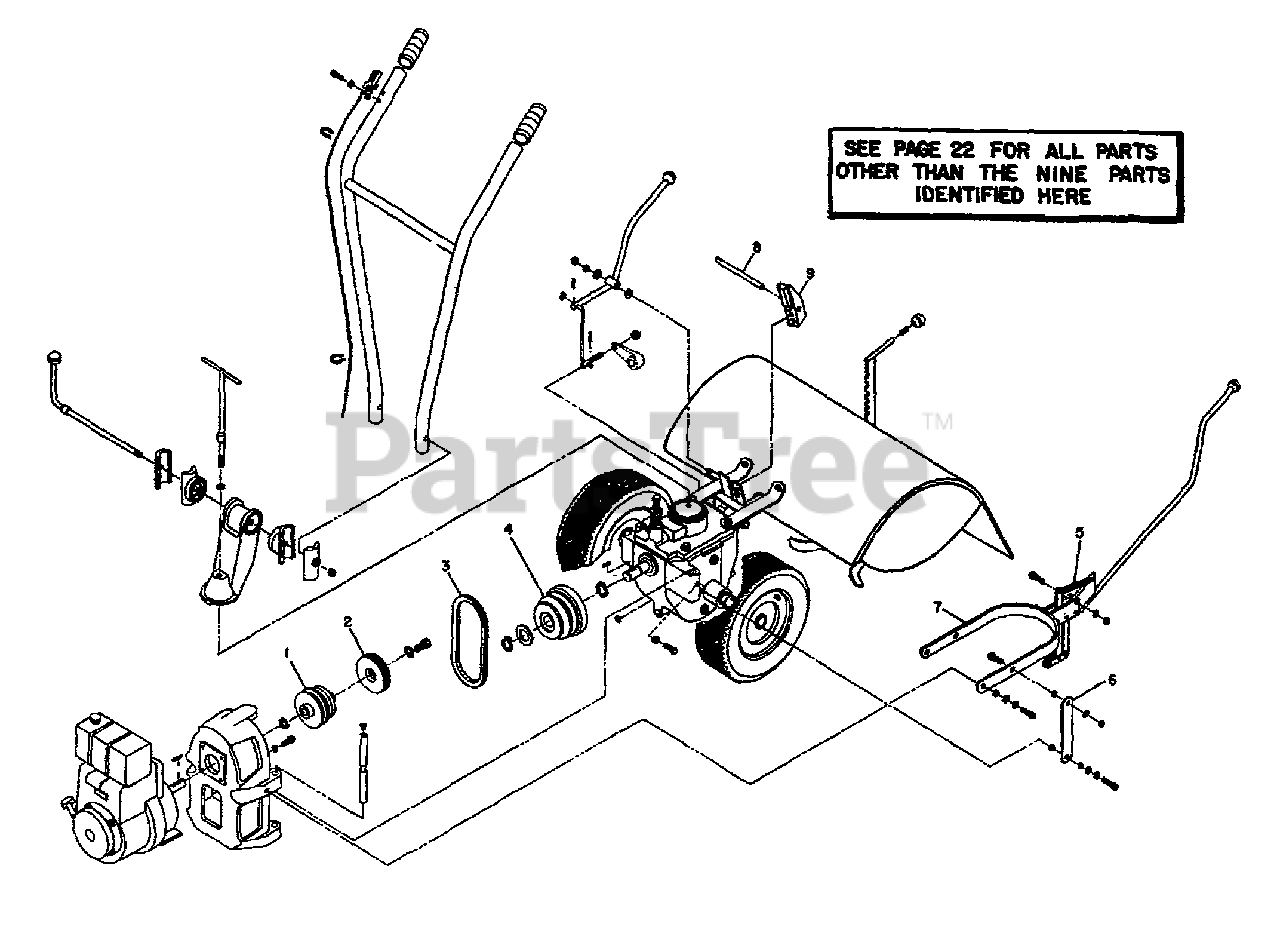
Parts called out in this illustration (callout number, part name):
1	PULLEY-ENG MACH
2	KIT-ADJ BLOCK/REV DISC
3	BELT-V
4	PULLEY-TRANS-MACH
5	SPRING-.436 X 3.25
6	BAR-CLUTCH YOKE
7	KIT-LEVER FWD/REV-HORSE 2
8	BAR-ADJUST
9	KIT-ADJ BLOCK 4 SP
